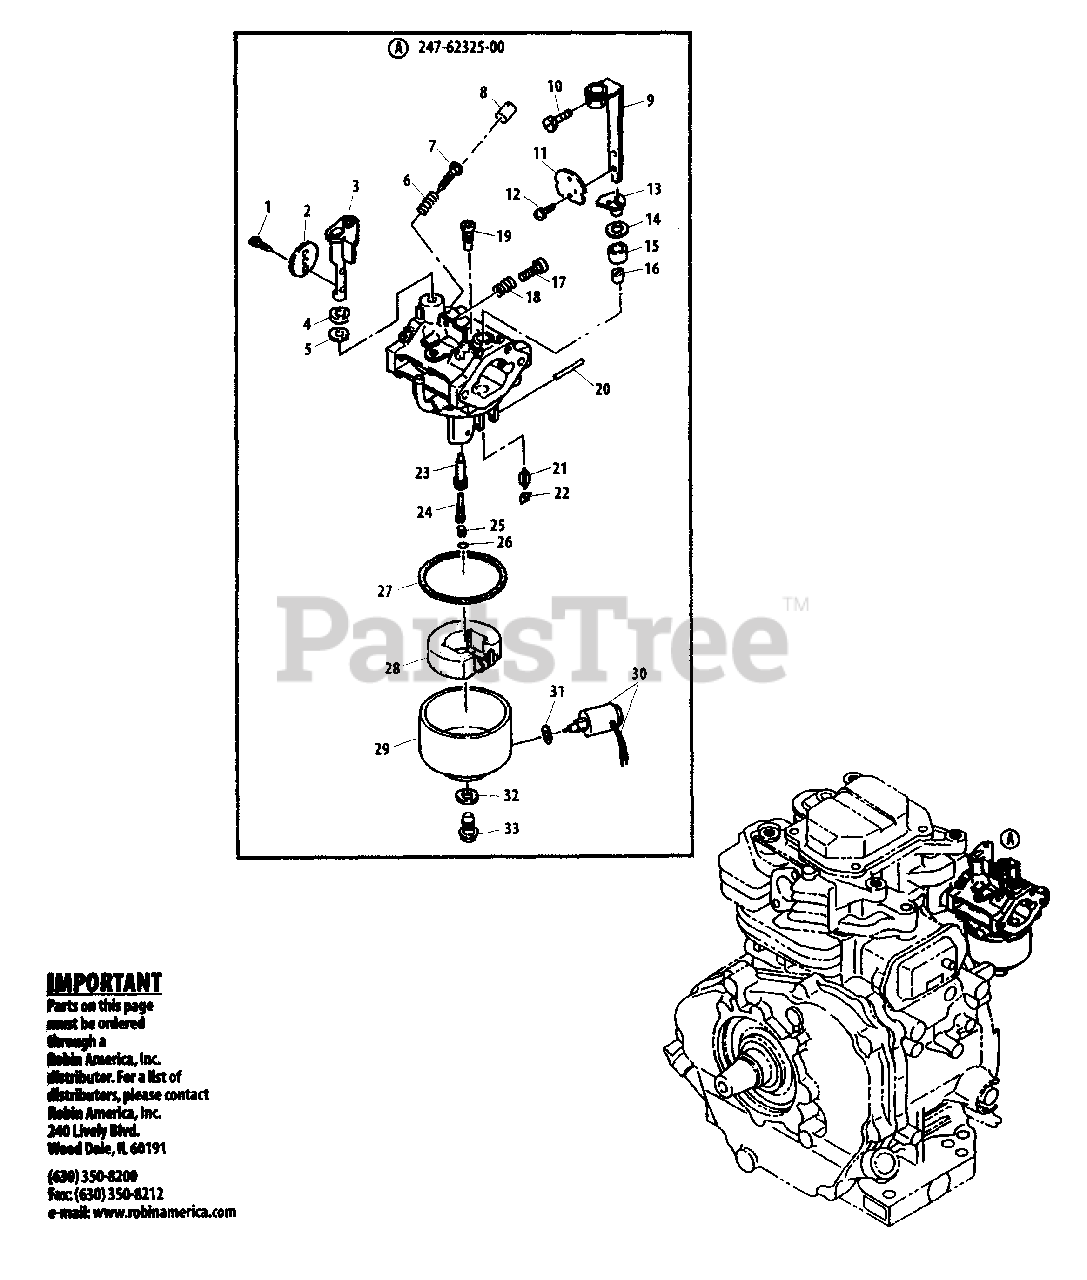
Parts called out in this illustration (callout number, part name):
1	SCREW
2	VALVE, THROTTLE
3	SHAFT, THROTTLE
4	PACKING
5	SEAL
6	SPRING
7	SCREW
8	CAP
9	SHAFT, CHOKE
10	BOLT
11	VALVE, CHOKE
12	SCREW
13	RING (CHOKE)
14	SEAL
15	CAP
16	RING
17	SCREW
18	SPRING
19	JET - 42.5
20	PIN
21	NEEDLE ASSY
23	MAIN NOZZLE
24	HOLDER
25	JET, MAIN
26	O-RING
27	GASKET, CHAMBER
28	FLOAT
29	BODY, FLOAT CHAMBER
30	SOLENOID ASSY
31	WASHER
32	WASHER
33	HOLDER, JET
